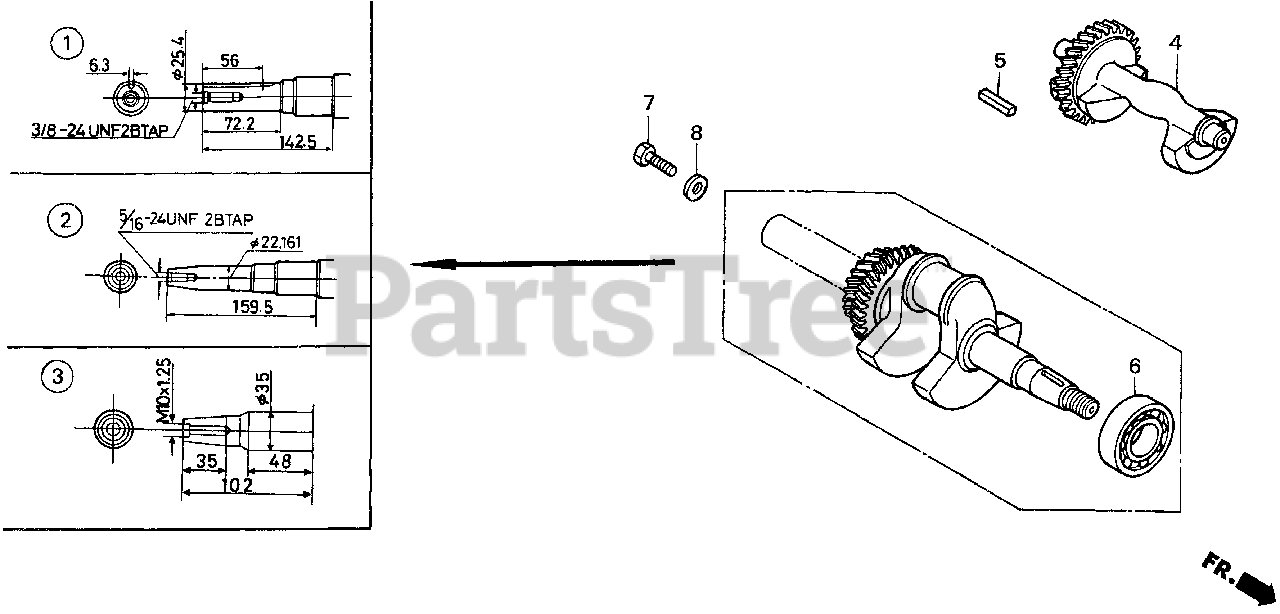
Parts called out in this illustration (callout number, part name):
3	CRANKSHAFT (E-TYPE)
4	WEIGHT, BALANCER
6	BEARING, RADIAL BALL (6207)
